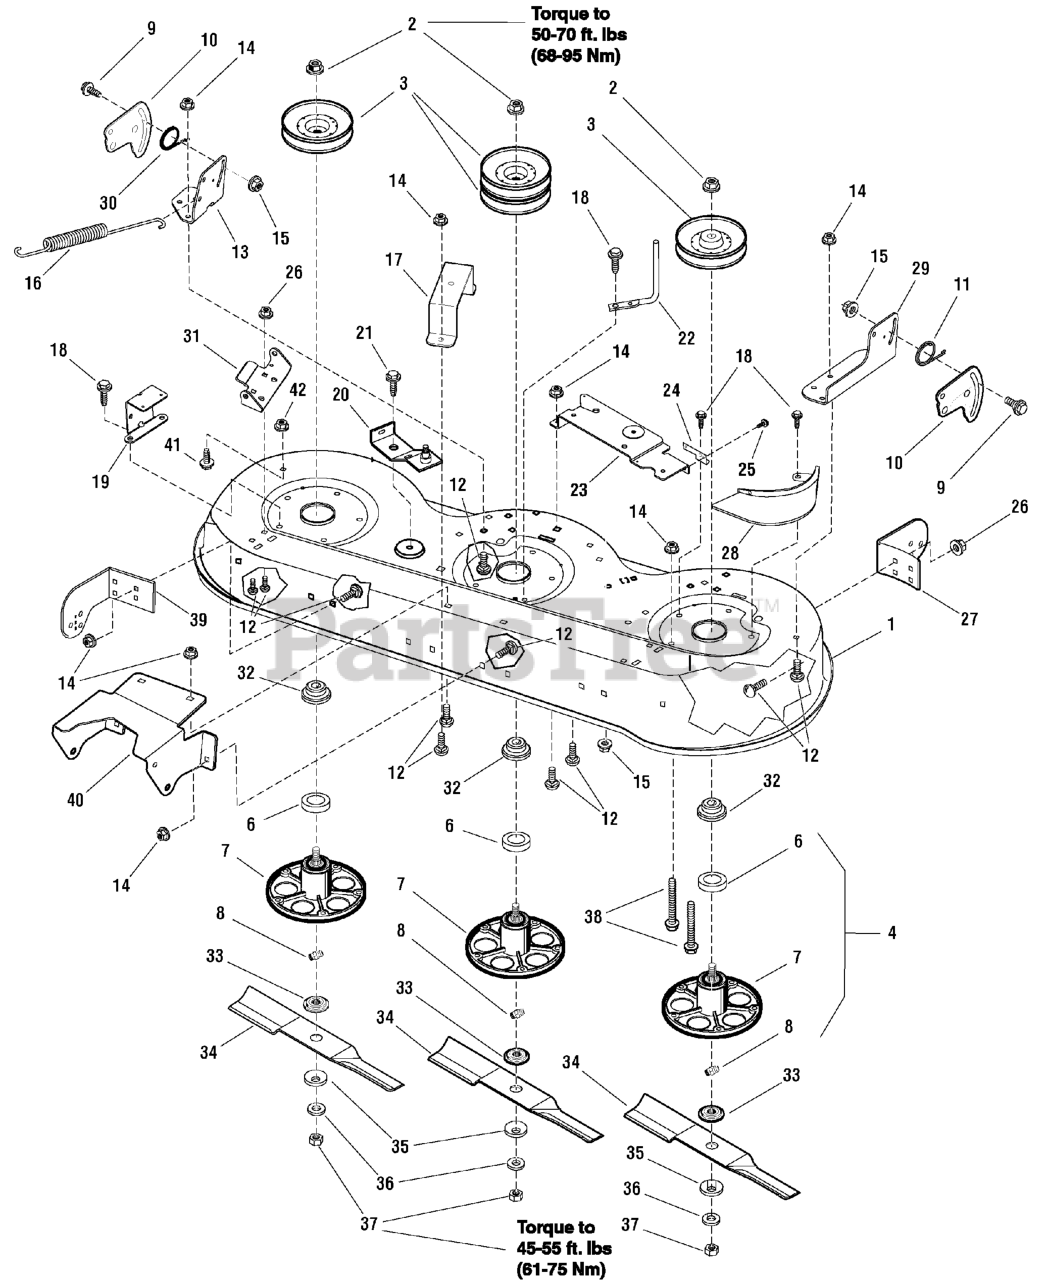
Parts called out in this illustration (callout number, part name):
1	HOUSING, Mower, 46 in
2	NUT, Nylock Ring, Pulley 9/16-18
3	PULLEY, Split Steel
4	JACKSHAFT HOUSING ASSY
6	BALL BEARING, Jackshaft
7	JACKSHAFT HOUSING
8	FITTING, Lubrication
9	BOLT, Shoulder, 3/8-16 x 1
10	BRACKET, Deck Suspension
11	SPRING, Right Torsion
12	BOLT, Carriage, 5/16-18 x 5/8
13	BRACKET, Right Rear
14	NUT, Hex Flange 5/16-18
15	NUT, Hex Flange, 3/8-16
17	BRACKET, Bellcrank
18	SCREW, Thread Forming 3/8-16 x 1-1/4
19	BRACKET, Cover
20	IDLER ARM, 46", Right
21	BOLT, Shoulder 3/8-16 x 3/4
22	GUIDE, Belt
23	BRACKET, Brake Mounting 46 in
24	BRACKET, Brake Plate
25	CAPSCREW, 5/16-18
26	NUT, Hex Flange Lock, 5/16-18
27	BRACKET, Left Gauge Wheel
28	BRACKET, Pulley Cover
29	BRACKET, Left Lift
30	SPRING, Left Torsion
31	BRACKET, Hinge
32	SPACER, Pulley
33	BLADE ADAPTER
34	BLADE, 46 in
35	WASHER, Belleville
36	WASHER, Hardened 1
37	NUT, Blade, 9/16-18
38	GUIDE, SCREW (5/16-18)
39	BRACKET, Right Gauge Wheel
40	BRACKET, Front Deck
41	BOLT, Carriage, 5/16-18 x 3/4
42	Retainer, Push
